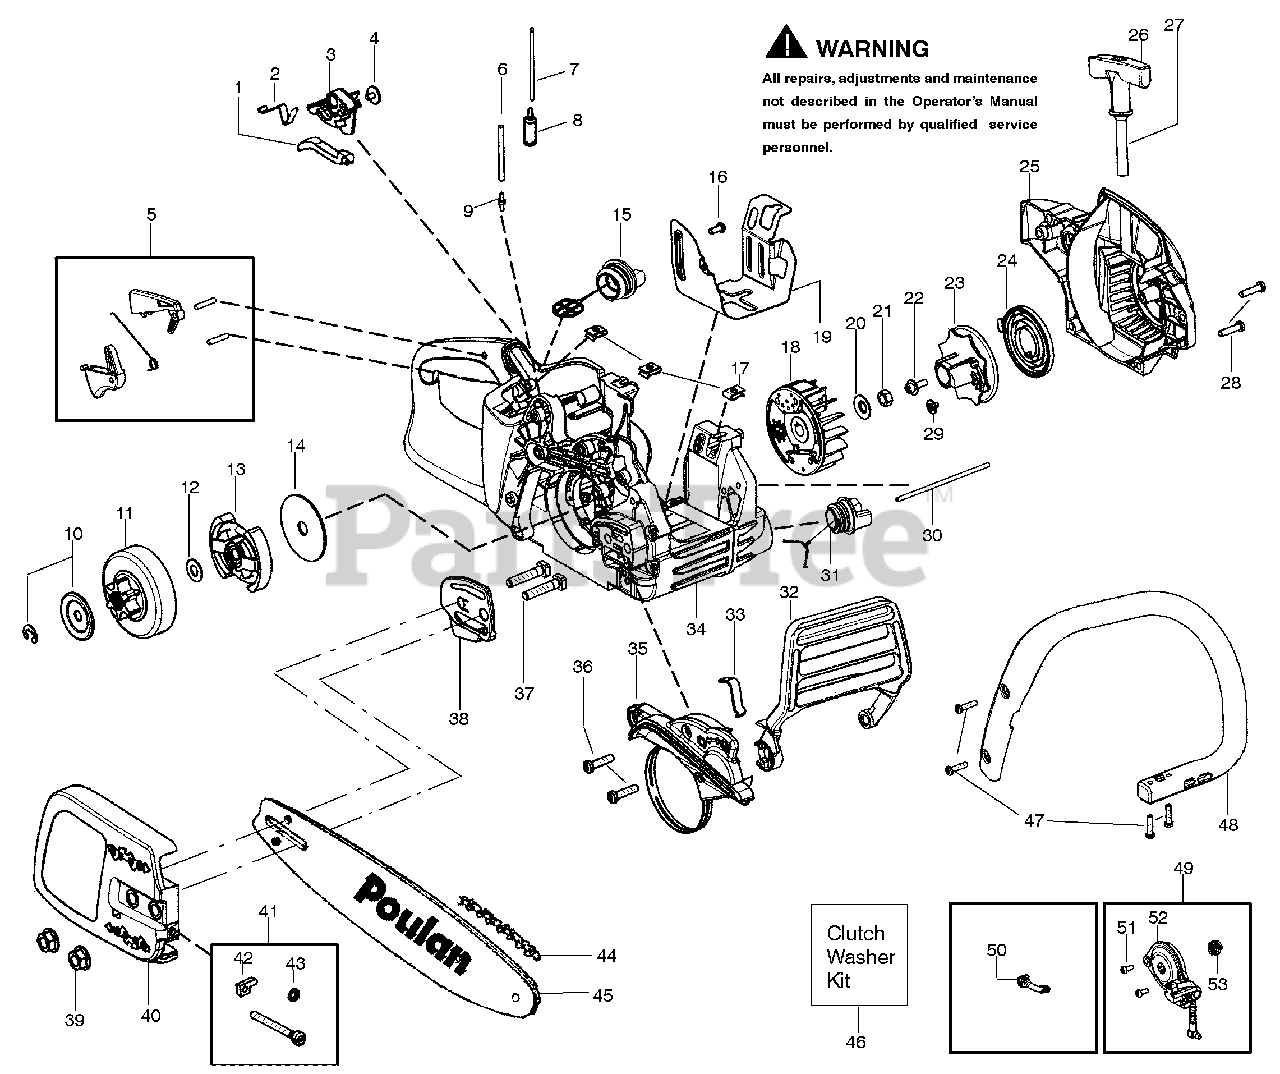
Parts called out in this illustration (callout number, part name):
1	Knob-Choke
2	Spring-Ign. Switch
3	Lever-Ign. Switch
5	Kit-Trigger/Lockout
6	Kit-Fuel Line
7	Kit-Fuel Line
8	Assy-Fuel Pick Up
9	Fitting-Fuel line
10	Kit-Clutch Washer
11	Assy-Clutch Drum 3/8"
12	Kit-Clutch Washer
13	Assy-Clutch
14	Washer-Large Clutch
15	Assy-Fuel Cap w/ret
17	Nut-"U" type speed
18	Assy-Flywheel
19	Shield-Heat
20	Washer-Flywheel
21	Nut-Flywheel
23	Pulley-Starter
24	Spring-Starter
25	Housing-Fan
26	Handle-Starter
27	Kit-Rope
30	Assy-Oil Vent
31	Assy-Oil Cap w/ret.
32	Handguard
33	Spring-Handguard
34	Assy-Chassis
35	Kit-Chainbrake
37	Bolt-Bar
38	Plate-Bar
40	Assy-Clutch Cover
41	Kit-Bar Adjust
42	Pin-Bar Adjust
43	Retainer-Bar Adjust
44	Accy-18" Chain
45	Accy-18" Bar
46	Kit-Clutch Washer
48	Handle-Front
49	Kit-Oil Pump
50	Assy-Oil Pick Up
52	Assy-Oil Pump
53	Gear-Worm
